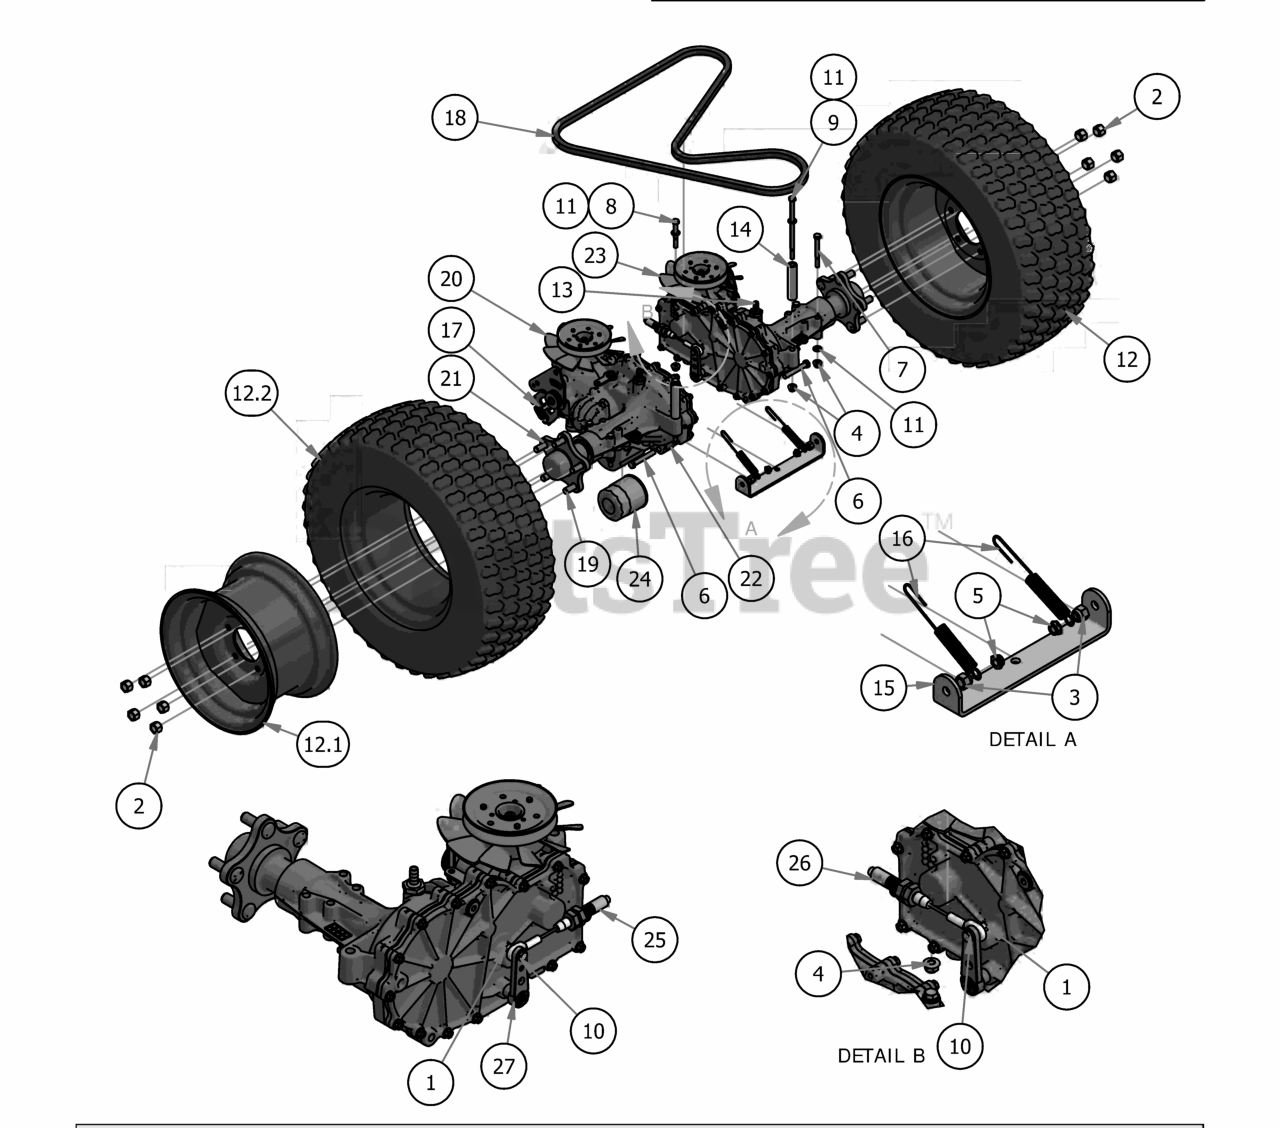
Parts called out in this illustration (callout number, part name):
1	1/4-20 Nylon Insert flange Nut
2	Acorn Lug Nut
3	3/8 Nylock Nut
4	5/16" Nylock Flange Nut
5	3/8 Nylock Jam Nut 1/2 Nut
6	3/8 x 2 1/2 Hex Tap Bolt
7	5/16" x 3" Hex Bolt
8	5/16" x 2 1/2" Bolt
9	5/16" x 6" Bolt
10	1/4" x 3/4" Hex Bolt
11	5/16" Flat Washer
12	23 x 9 -12 Reaper Turf Wheel & Tire Assembly
12.1	12 x 7 Black Wheel
12.2	23 x 9 -12 Reaper Turf Tire
13	45 degree fitting
14	2017 Transaxle Spacer
15	Crossover Bar for ZT
16	Brake Spring
17	Transaxle Spring
19	Transaxle Wheel Studs
20	Fan/Pully kit
21	Transaxle Hub
22	Left 3400 IZT
23	Right 3400 IZT
25	Brake Cable,18.5"
26	Brake Cable, 24.5"
27	Transaxle Brake Lever
